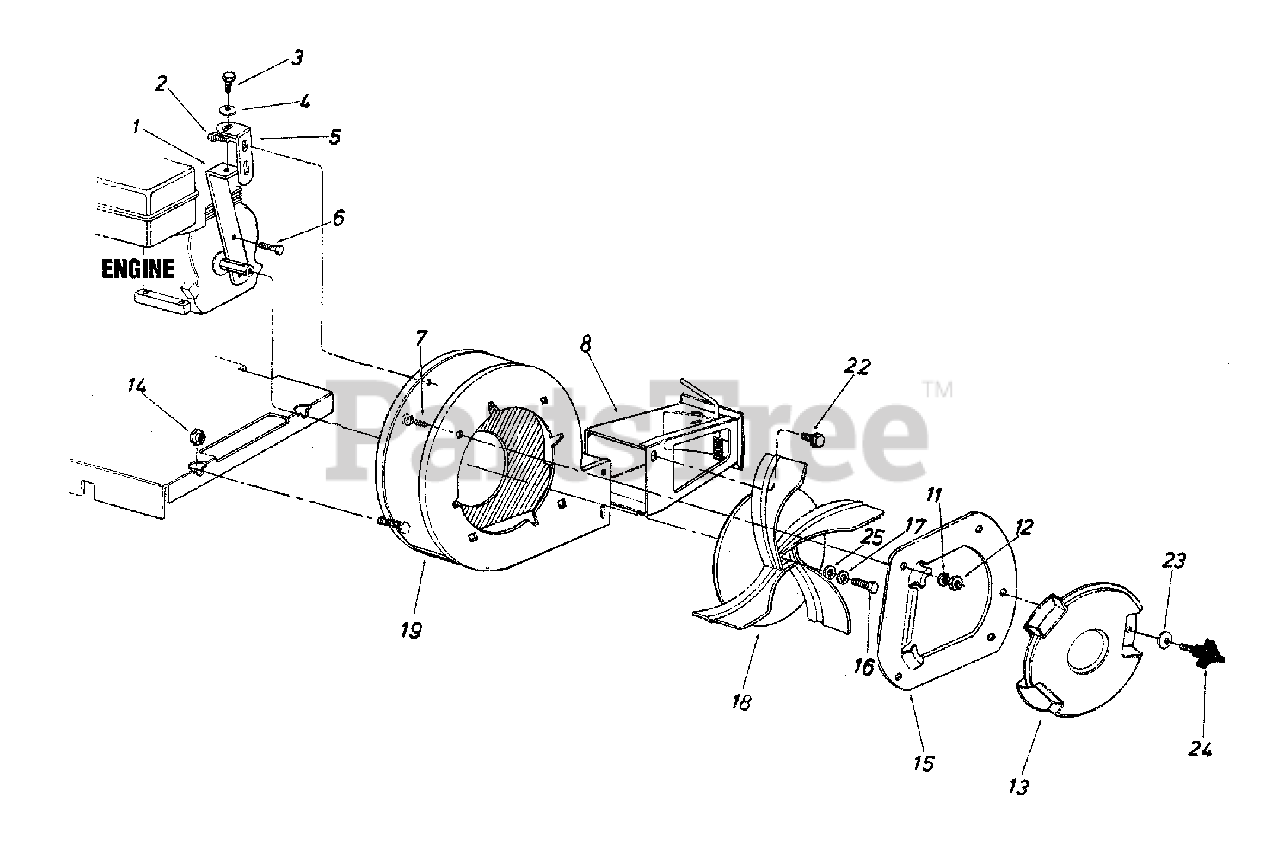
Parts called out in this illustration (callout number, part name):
3	Hex Bolt 5/16-18 x .75
4	Lock Washer 5/16"
7	Carriage Bolt 5/16-18 x .62
12	Hex Nut 5/16-18
13	Blower Guard
14	Hex Shoulder Nut .50"
17	Lock Washer 3/8
18	Air Vane Plate Assembly
23	Bell Washer .34 ID x .87 OD
24	Three Arm Screw 5/16-18 x .75
25	Flat Washer
